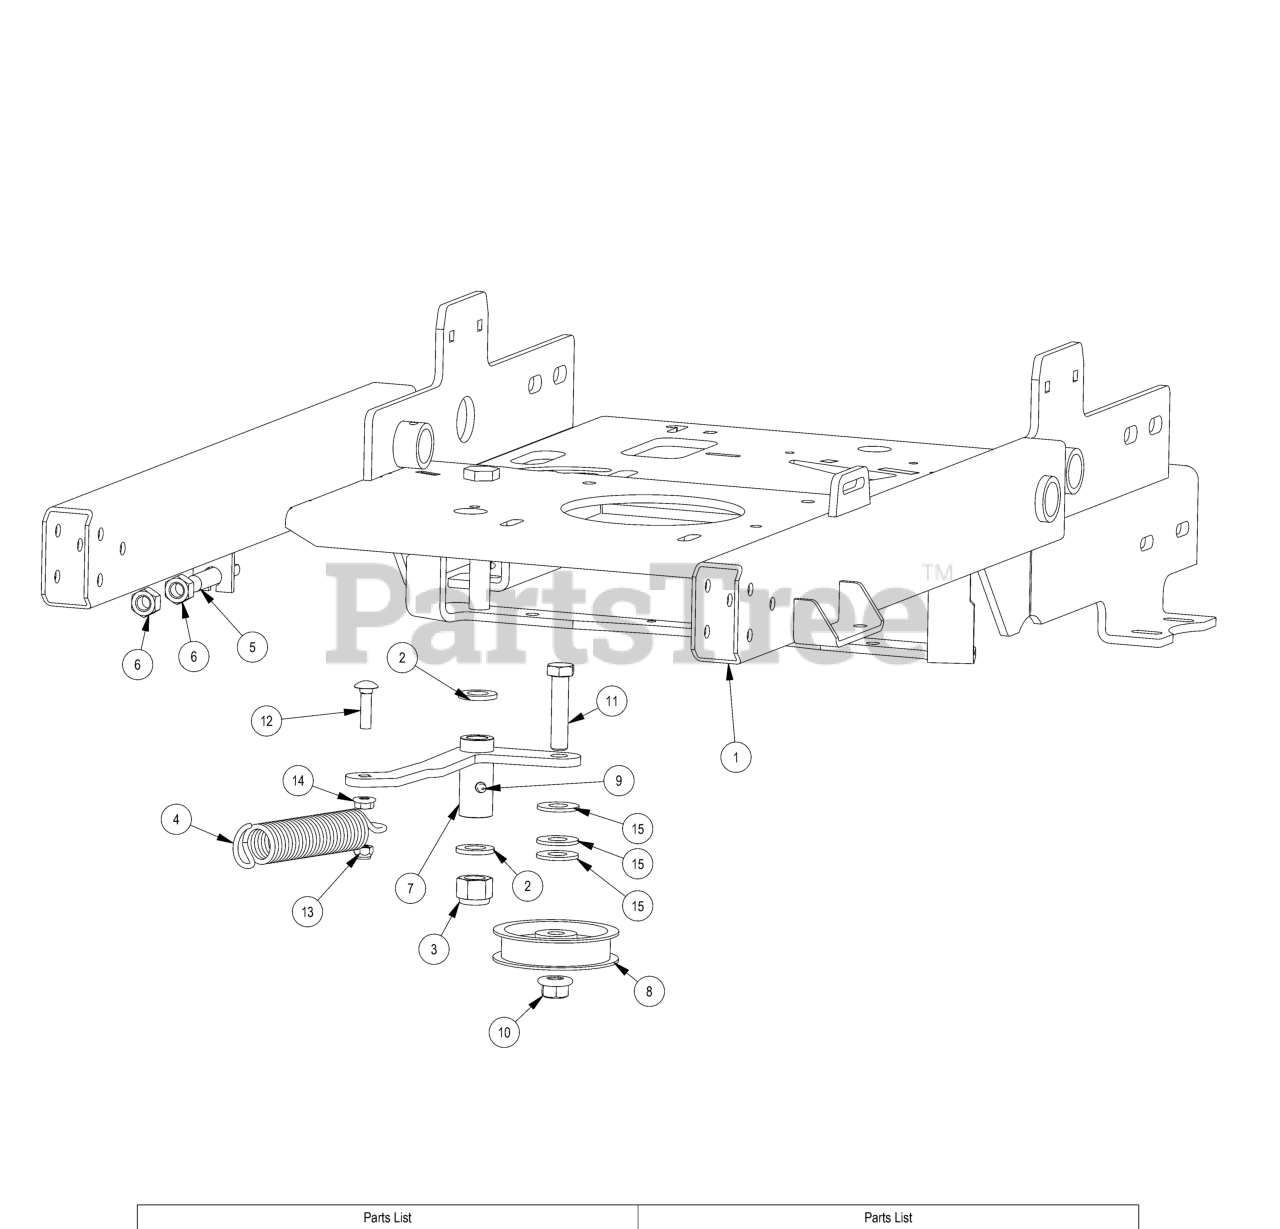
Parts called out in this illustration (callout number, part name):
1	2020 36" Stand On Frame
2	.630 ID x 1.122 OD x .142 THK Plastic Washer
3	5/8 Std NC Nylock Nut
4	Deck spring big diameter
5	All Thread
6	1/2-13 HEX NUT ZINC
7	36 Pump Idler Arm Weldment
8	3.25 Flat Idler Pulley
9	1/4" Press in Grease Fitting
10	1/2-13 NYLON INSERT FLANGE LOCKNUT ZINC
11	1/2-13 X 2-1/4 HEX CAP SCREW (GR.5) ZINC
12	5/16-18 X 1-1/4 CARRIAGE BOLT ZINC
13	5/16-18 NYL INS L/N ZC
14	5/16-18 HEX SERRATED FLANGE NUT HARD/ZINC
15	.565 ID X 1.250 OD X .095 THK FLAT WASHER BRASS
